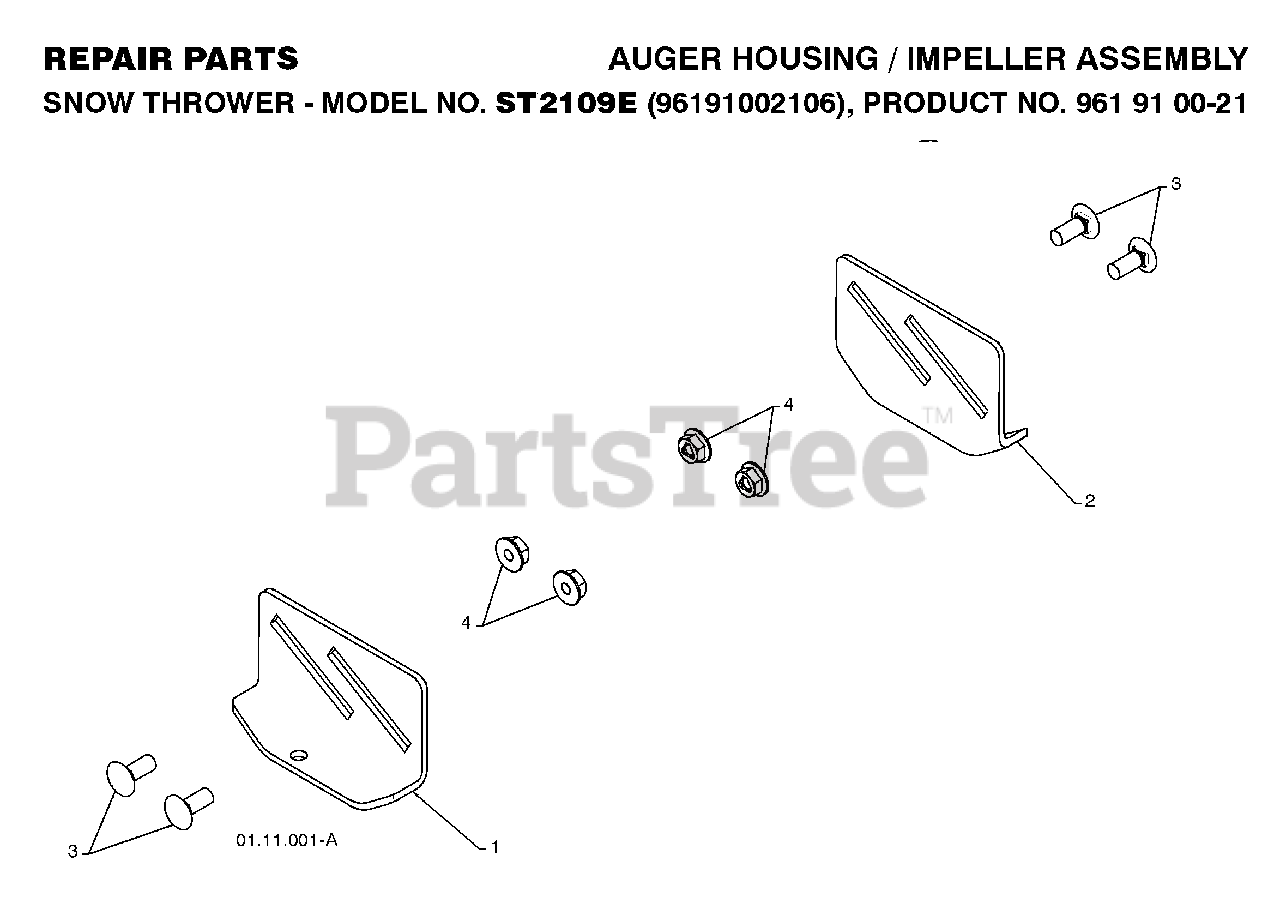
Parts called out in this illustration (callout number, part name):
1	SKID PLATE LH
2	SKID PLATE RH
4	NUT, LOCK 5/16-18
